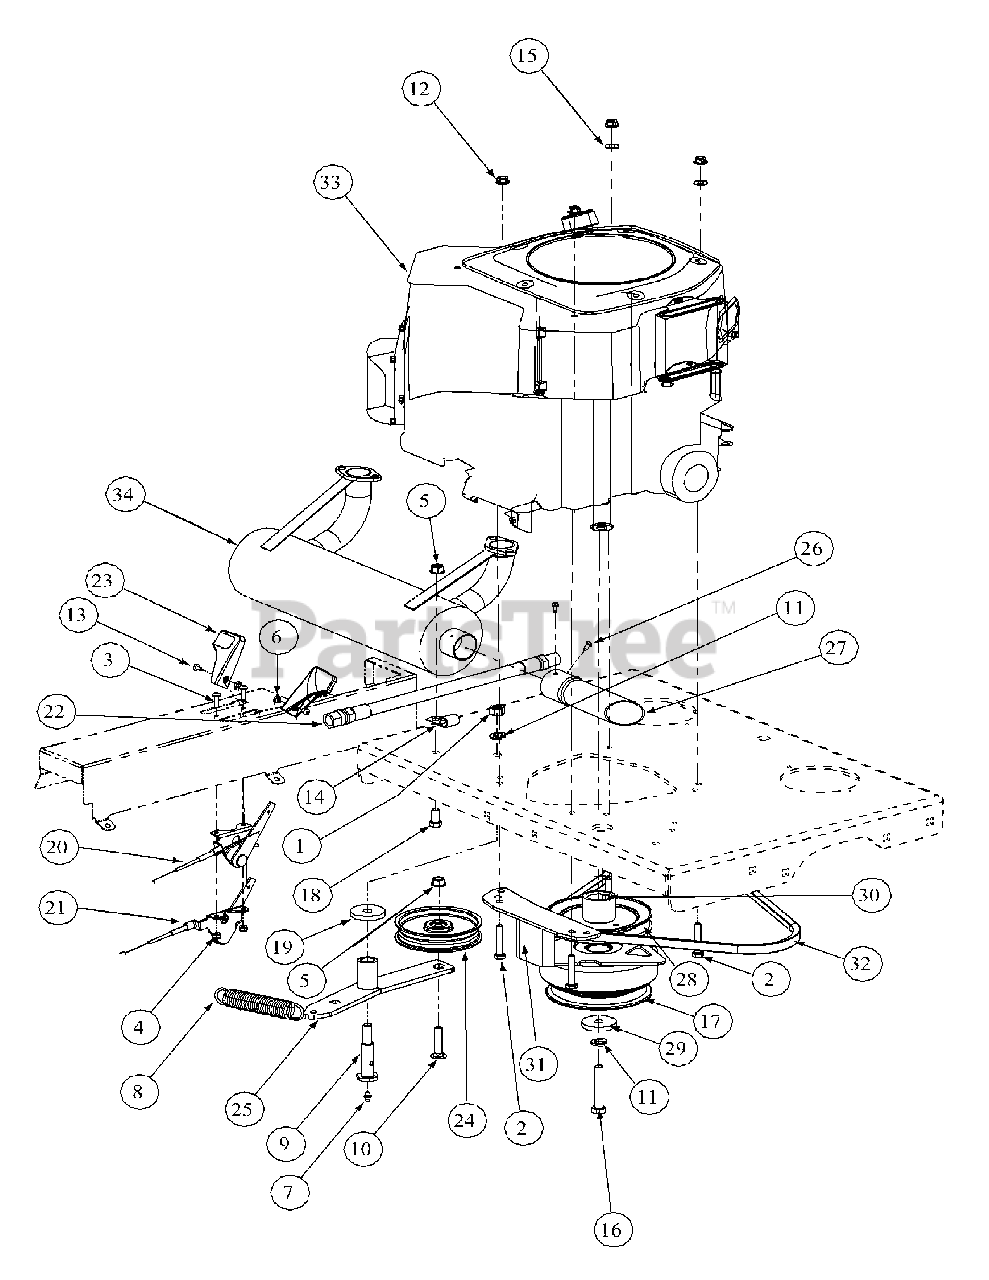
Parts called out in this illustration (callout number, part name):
1	Hex Nut, 7/16-14
2	HHCS, 5/16-18, 1-3/4
3	Round Hd. Machine Screw, 10-32 x 3/4
4	Lock Nut, Nylon Insert, 10-32
5	Flange Lock, Hex Nut, 3/8-16
6	Nut Washer, W/Star, 8-32
7	Grease Fitting, 1/4-28 x 3/16
8	Extension Spring, 1.0 OD x 5.125
9	Shoulder Screw, 7/16-14
10	Hex Carriage Screw, 3/8-16, 1.75
11	Lock Washer, 7/16
12	Hexflange Lock Nut, 5/16-18
13	Machine Screw, 8-32, .375
14	Clip, Heat Shield Cable
15	Flat Washer, 5/16
16	Capscrew, 7/16-20 x 2.50
17	Clutch Brake, 1.125 ID
18	Hex Cap Screw, 3/8-16, .750
19	Flat Washer, 7/16 ID x 1.75 OD x .25
20	Choke Control Cable
21	Throttle Control Cable
22	Oil Drain Hose
23	Control Throttle Knob
24	Flat Pulley with Flanges
25	Engine Idler Arm Assembly includes Bearing
25	Bearing
25	Engine Idler Arm Assembly Cast
26	Screw, #8-32, 0.375 Hxindwsh
27	Straight Exhaust Pipe, Selxsys
28	Pump Drive Pulley
29	Flat Washer, 7/16 ID x 1.75 OD x .25
30	Key, 1/4 x 1/4 x 3
31	Retainer Clutch Assembly, Ogura
32	Belt, 51.2 Lg
33	Engine, 25HP Kohler
34	Muffler Accessory Kohler
